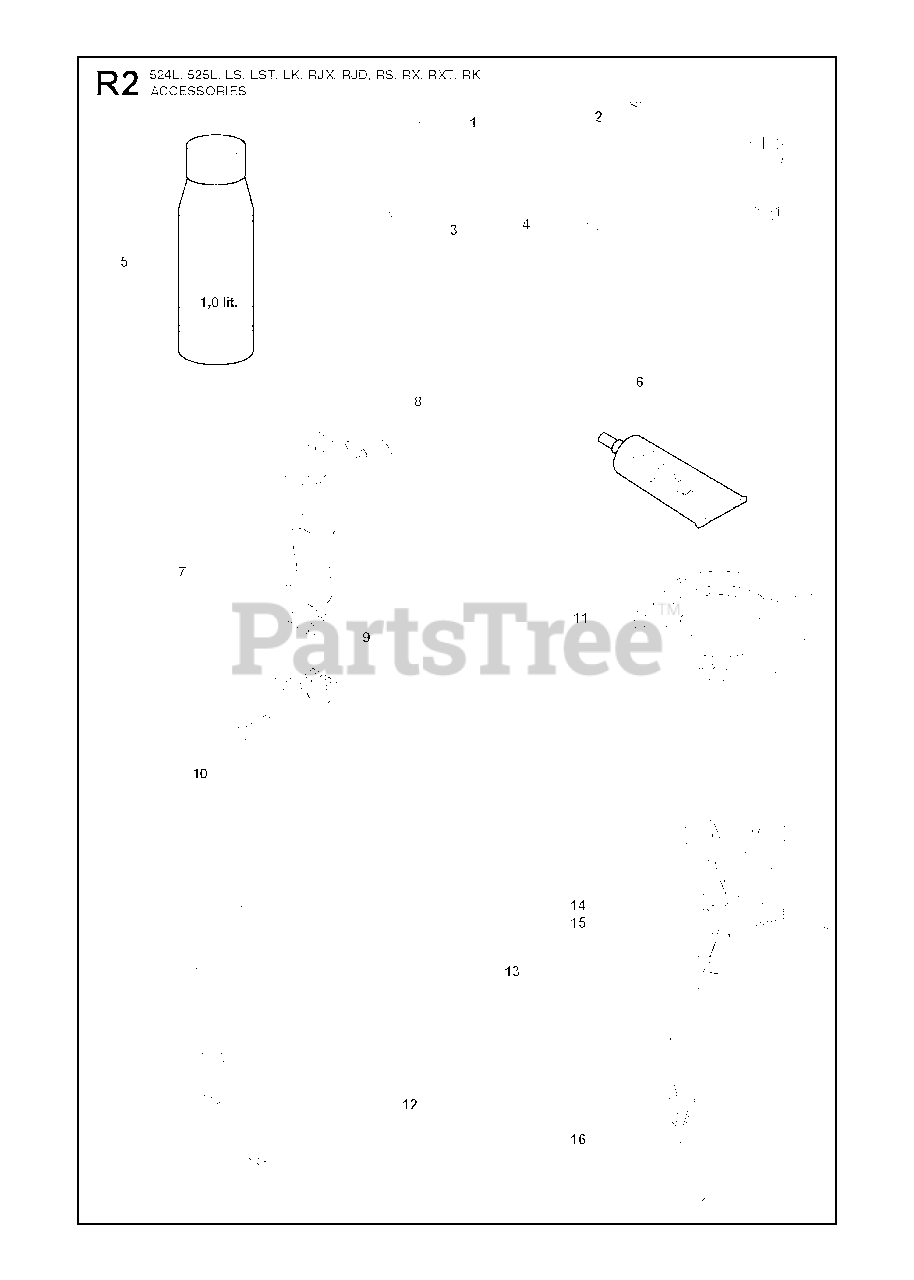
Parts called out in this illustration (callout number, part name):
1	LOCKING PIN
2	COMBINATION WRENCH TORX
3	SCREWDRIVER
4	L-KEY WRENCH
5	Air Filter Oil, HVA 1L Bottle
6	BEVEL GEAR GREASE
7	HANGING BRACKET
8	KNOB
9	HOOK
10	SCREW M6S 5X20
11	BLADE GUARD TRANSPORT
12	STRAP
12	Shoulder Strap with Sign
13	HARNESS DUO
13	Hip Pad Harness
14	BUCKLE
15	STRAP
16	HOOK, CPL.
